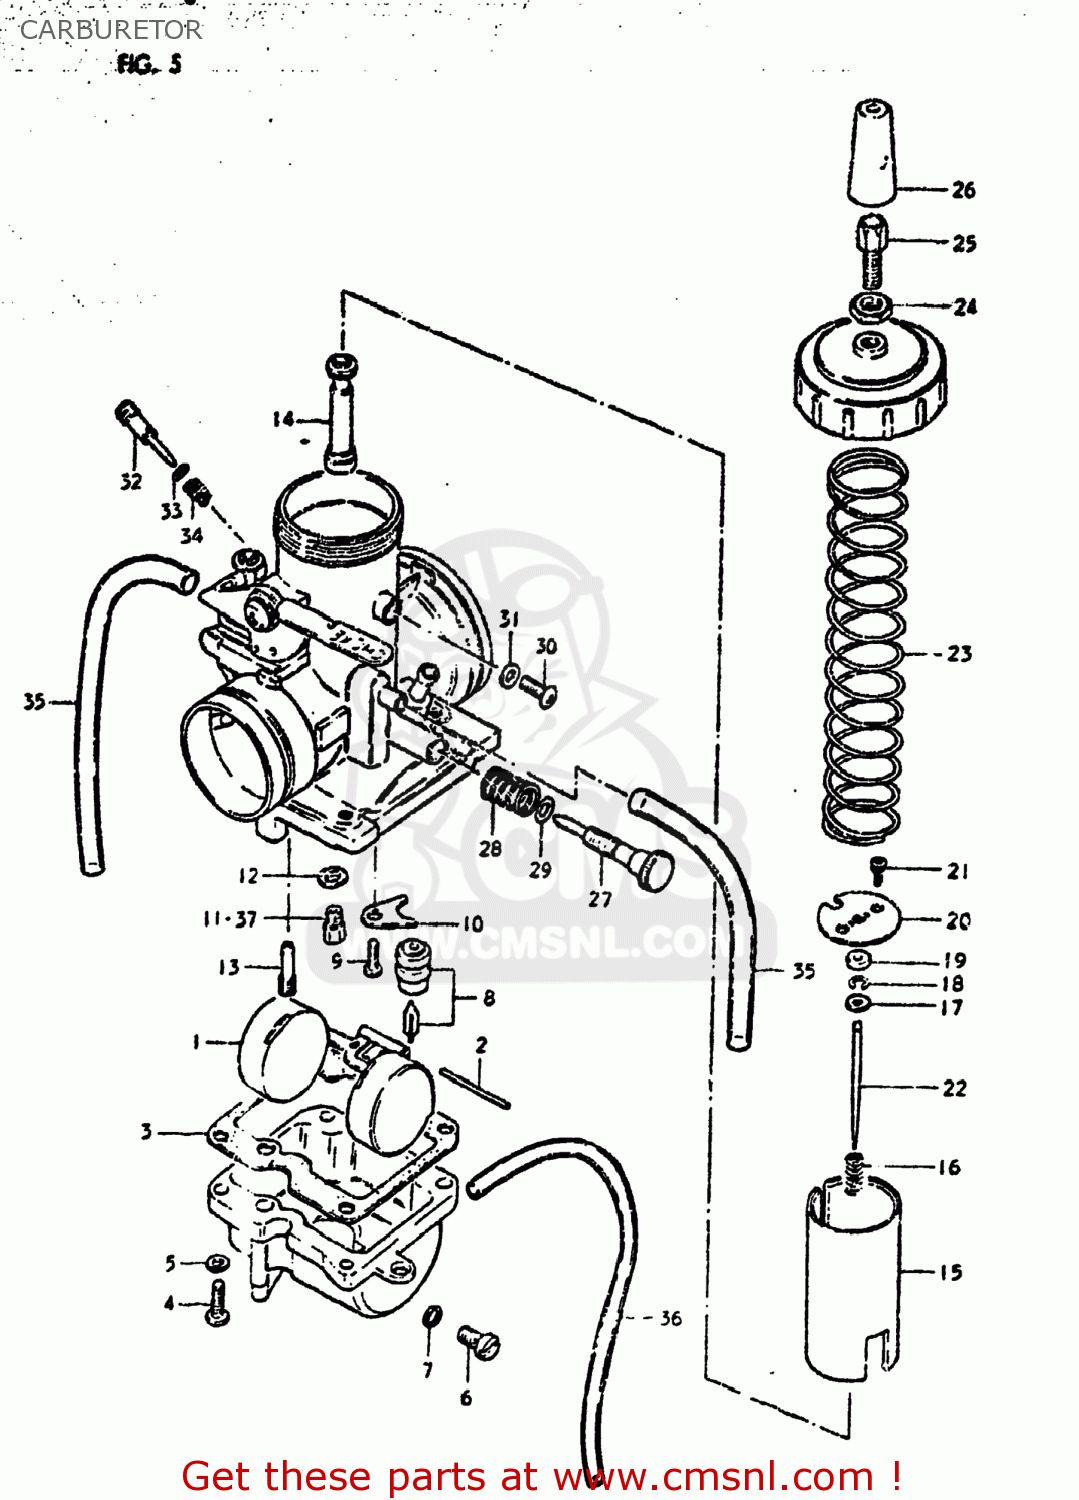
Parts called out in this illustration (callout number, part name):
1	FLOAT
2	PIN,FLOAT
3	GASKET,FLOAT CAHMBER (NAS)
4	SCREW
5	LOCK WASHER
6	PLUG
7	GASKET,DRAIN,PLUG (NAS)
8	VALVE ASSEMBLY,NEEDLE
9	SCREW
10	PLATE
11	JET
12	WASHER
13	JET
14	JET,NEEDLE
15	VALVE,THROTTLE
16	SPRING
17	WASHER,JET NEEDLE
18	CLIP
19	RING
20	PLATE
21	SCREW
22	NEEDLE,JET
23	SPRING, THROTTLE VALVE
24	NUT
25	ADJUSTER,CABLE
26	CAP
27	ADJUSTER
28	SPRING
29	O-RING
30	SCREW
31	RING
32	SCREW,PILOT AIR
33	O RING
34	SPRING
35	HOSE
36	HOSE
37	JET
